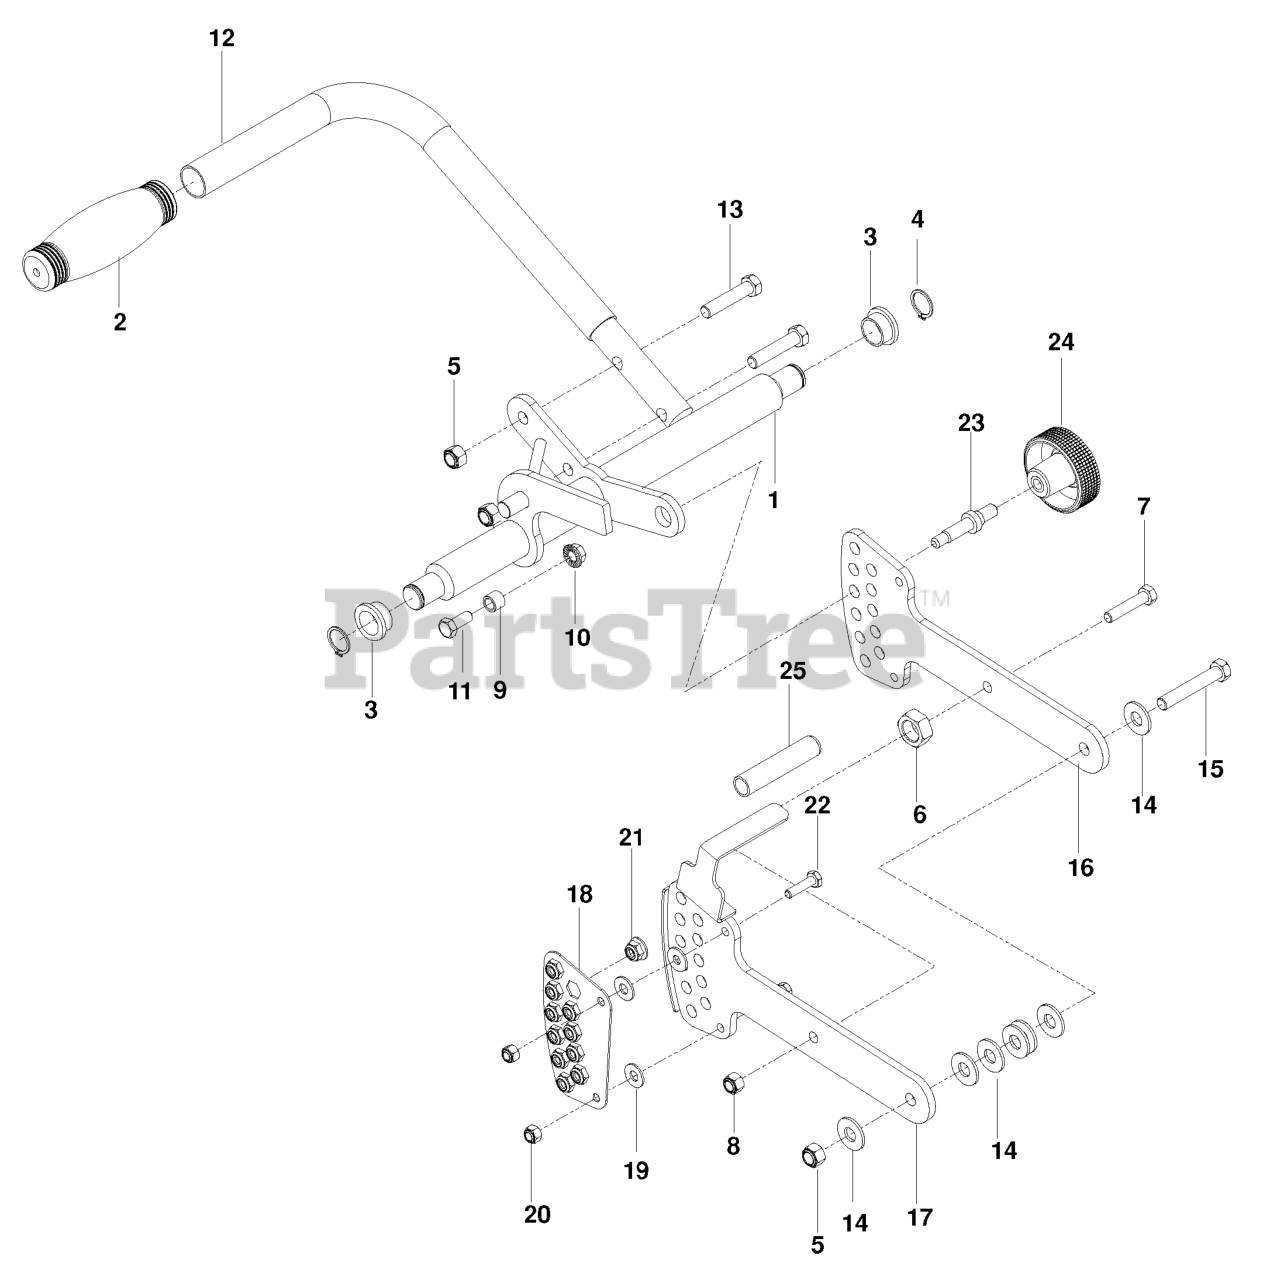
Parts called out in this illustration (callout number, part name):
1	D.O.C. SHAFT WLDMT, BLACK
2	GRIP HANDLE
3	BEARING - FLANGE
4	SNAP RING - .75
5	NUT 3/8-16 NYLOC
6	NUT 5/8F HEX
7	CAPSCREW 5/16 X 1/1/2 HEX HEAD
8	NUT 5/16 NYLOC
10	NUT 5/16C WHIZ
11	HCS 5/16C X 3/4
12	HANDLE D.O.C. GREY
13	HCS 3/8-16 X 1 3/4 GR5
14	WASHER 3/8 FLAT
15	HCS 3/8C X 2 1/4
16	ADJUSTER D.O.C., GREY
17	ADJUSER WLDMT RH, GREY
18	PLATE-ADJUSTER NUT, GREY
19	WASHER 1/4 FLAT
20	NUT.1/4-20.HEX.NYLOC.ZD
21	5/16-18 NYLOC FLANGE NUT
22	HCS 1/4 X 1
23	ADJUSTER, STUD
24	KNOB
